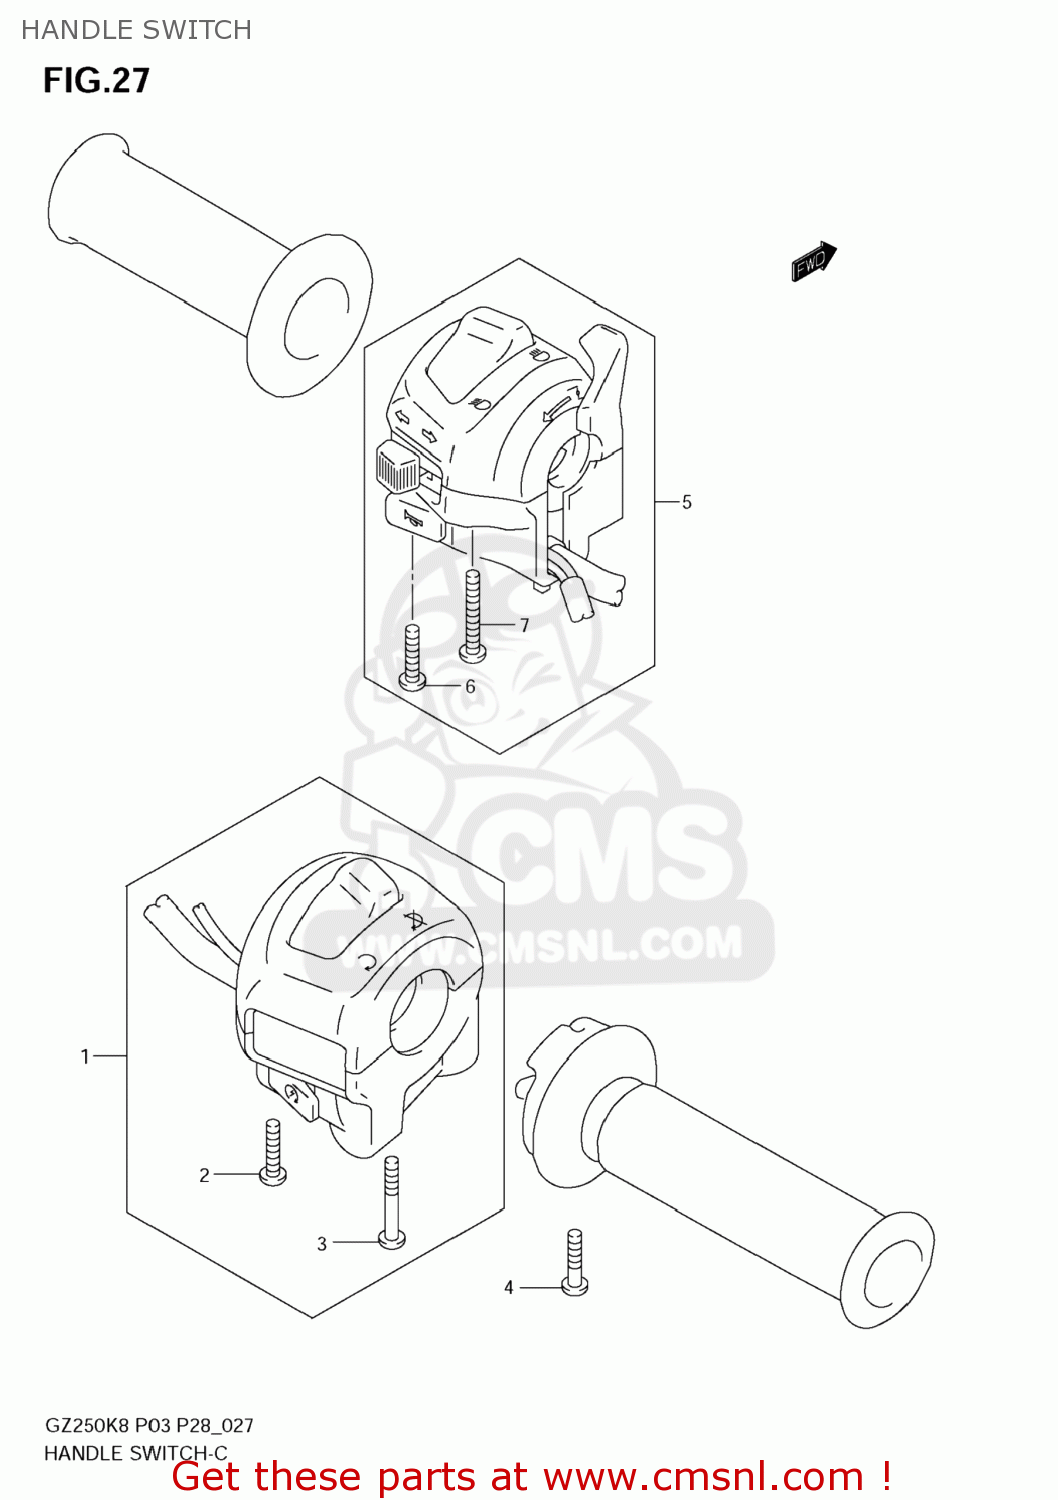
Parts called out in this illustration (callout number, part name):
1	SWITCH ASSY RH
2	SCREW
3	SCREW
4	SCREW
5	SWITCH ASSY, HANDLE LH
6	SCREW
7	SCREW
